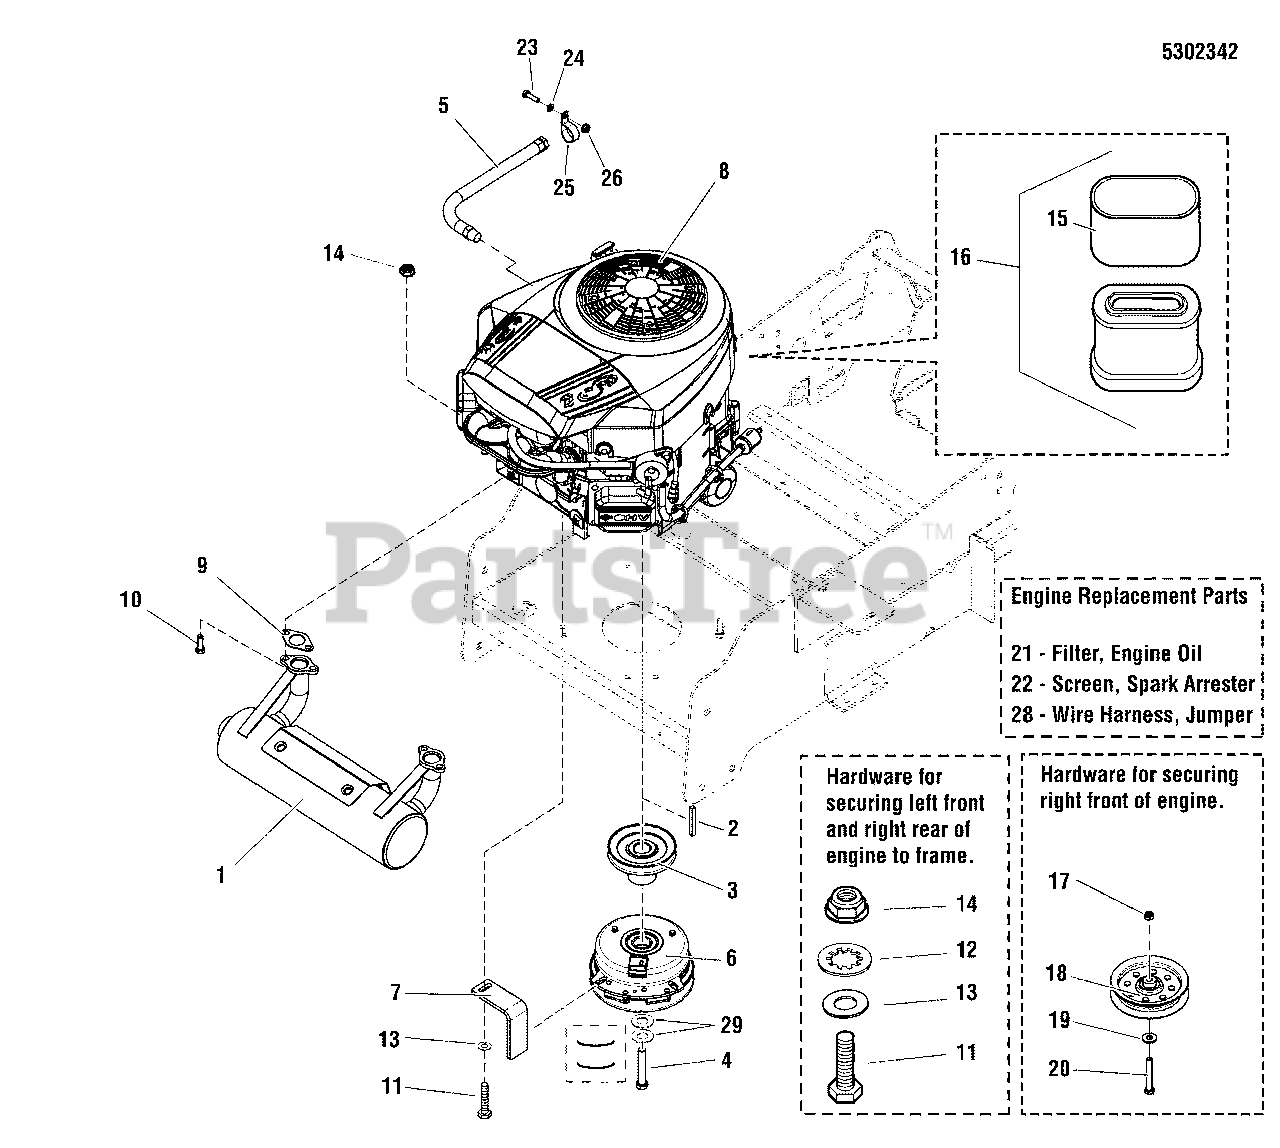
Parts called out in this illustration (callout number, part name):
1	MUFFLER, RIGHT OUTLET ASSY
2	KEY, 1/4 SQ. X 1.00
3	PULLEY, PUMP DRIVE, 4.857 OB X 1" BORE
5	HOSE, OIL DRAIN
6	CLUTCH, # 5219-34A, ELECTRIC, IS500Z
7	ANCHOR, CLUTCH - BLK
8	ENGINE, B&S
9	GASKET, EXHAUST
11	BOLT, 5/16-18 X 1-3/4 GD5 YZ
12	WASHER, 5/16" INT. TOOTH LOCK
13	WASHER, 5/16 SAE
14	NUT, 5/16-18 HEX NYLON LOCK
15	PRE CLEANER (SV)
16	AIR CLEANER W/ PRE CLEANER (SV)
17	SEE PUMP DRIVE GROUP
18	SEE PUMP DRIVE GROUP
19	SEE PUMP DRIVE GROUP
20	SEE PUMP DRIVE GROUP
23	BOLT, 1/4-20 X 1", GD
24	WASHER, 1/4 SAE (5025154)
25	CLAMP, VINYL INSULATED
26	NUT, 1/4-20 HEX NYLOCK FLANGE (5025391)
29	BELLEVILLE WASHER 1.1875 X .442 X .089
